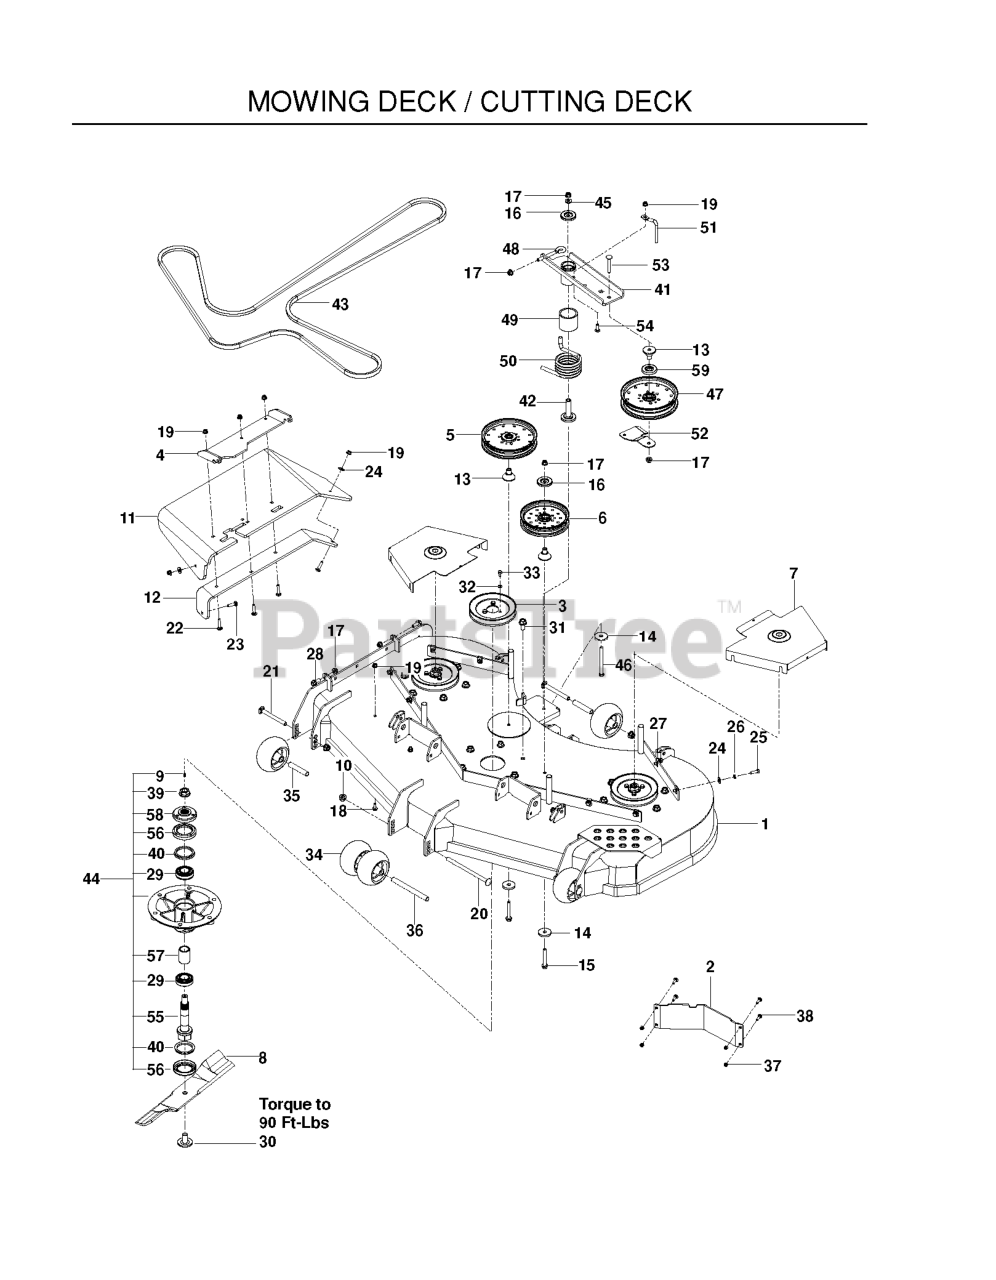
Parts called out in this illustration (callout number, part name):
1	DECK.SVC W/DECALS.60.ORANGE
2	BAFFLE, DIVERTER 54"/60" LH
3	PULLEY - 6.57
4	BRKT - CHUTE MTG BLACK
5	PULLEY - 7" NARROW
6	PULLEY IDLER, 6" NARROW
7	SHIELD,BELT, 60" ORANGE
8	BLADE - HEAVY DUTY 21"
9	ZERK
10	NUT, 1/2-13 HEX FLG NYLOC ZD
11	CHUTE, DISCHARGE 48-52
12	BRKT, CHUTE SUPPORT BLACK
13	BEARING, IDLER ARM
14	SPINDLE WASHER
15	HHFS 3/8-16 X 2 3/4
16	DUST SHIELD
17	NUT 3/8-16 HEX FLG NYLOC ZD
18	HHFS 5/16-18 X 3/4
19	5/16-18 NYLOC FLANGE NUT
20	RHSNB 1/2-13 X 8 GR5 ZD
21	RHSNB 1/2-13 X 4.75 GR5 ZD
22	RHSNB 5/16-18 X 1-1/2 GR 5 ZD
23	BOLT, CARRIAGE 5/16X1-1/4
24	WASHER 5/16 FLAT
25	HCS 5/16C X 1
26	WASHER.LOCK.HVY.HLCL.SPR.5/16
27	U-CLIP 5/16-18 NUT RETAINER
28	HHFS 3/8-16 X 1 GRD 5 ZD
29	BEARING - 206KRR8
30	BLADE BOLT/WASHER
31	HHFS 1/2-13 X 1 GR5 ZD
32	WASH 5/16 DISC SPRING ZD
33	HCS 5/16-18 X 1/2 GR 5 ZD
34	ROLLER, GAUGE .635 BORN
35	TUBE, ROLLER AXLE
36	TUBE, ROLLER AXLE LONG
37	NUT.1/4-20.HEX.NYLOC.ZD
38	1/4-20X3/4 CARR BLT
39	NUT FLANGE 3/4-16
40	V-RING, 55MM
41	ASSY, IDLER ARM, PZ
42	BEARING, IDLER PIVOT
43	BELT, "B", 176
44	SPINDLE ASM. 10"
45	WASHER, 3/8 THICK
46	HCS 3/8-16 X 4-1/2 GR 8 ZD
47	PULLEY - IDLER 7"
48	EYE BOLT, 3/8 X 4"
49	SPACER, IDLER PIVOT
50	SPRING, TORSION, IDLER
51	BELT KEEPER
52	BELT.GUIDE.BLACK
53	CARRIAGE BOLT 3/8-16 X
54	RHSSNB 5/16C X 1.0
55	SHAFT - SPINDLE
56	CUP - DEBRIS
57	SPACER - BEARING
58	HUB - PULLEY
59	SHIELD, DUST
